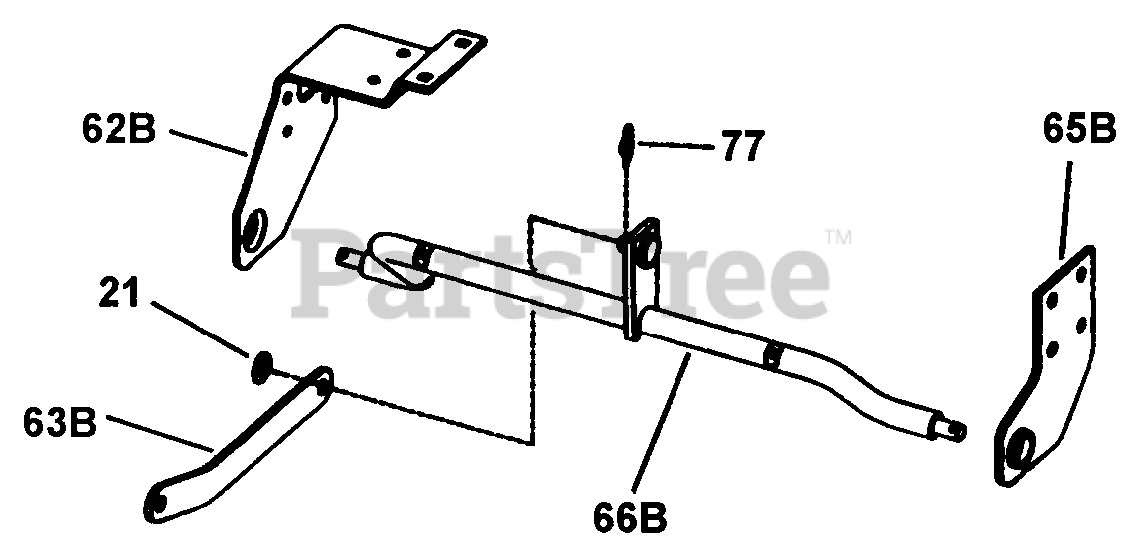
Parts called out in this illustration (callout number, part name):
21	WASHER, 3/8 Bright Zinc, Flat
62B	BRACKET, Rear Lift/PTO Lever
63B	LINK, Lift
65B	BRACKET, Rear Hanger- LH
66B	WELDMENT, Rear Lift
77	COTTER PIN, 1/16 x 1-7/32" Self Lock
